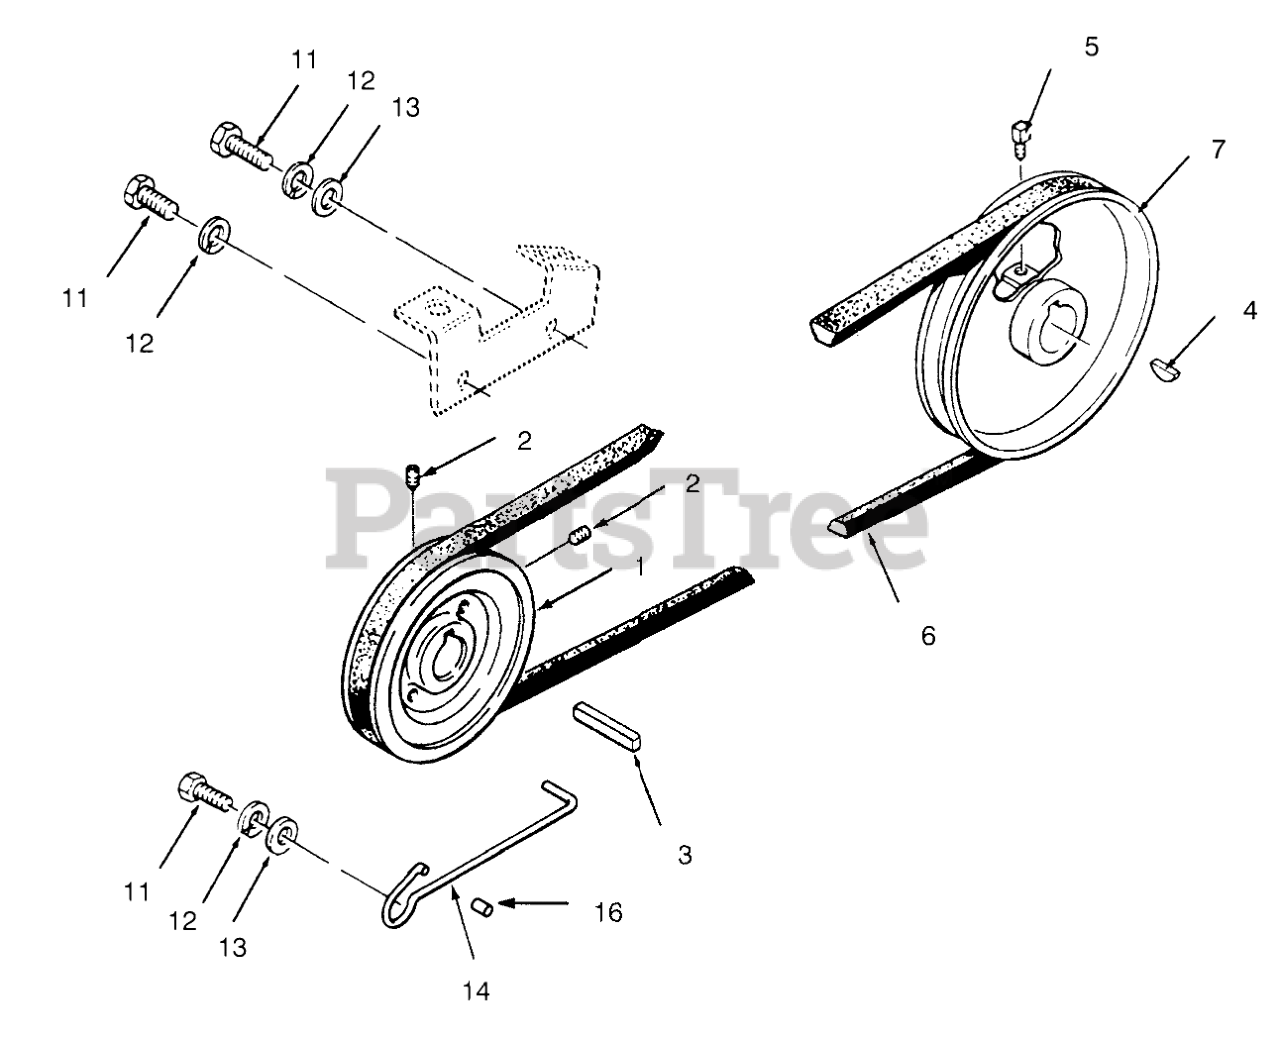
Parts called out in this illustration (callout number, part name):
1	PULLEY
2	SCREW-SET, HSH
4	KEY-HI PRO
5	SCREW-SQH
6	V BELT
7	PULLEY-TRANSMISSION
11	SCREW-HH
12	WASHER-LOCK
13	WASHER-FLAT
14	GUIDE BELT
